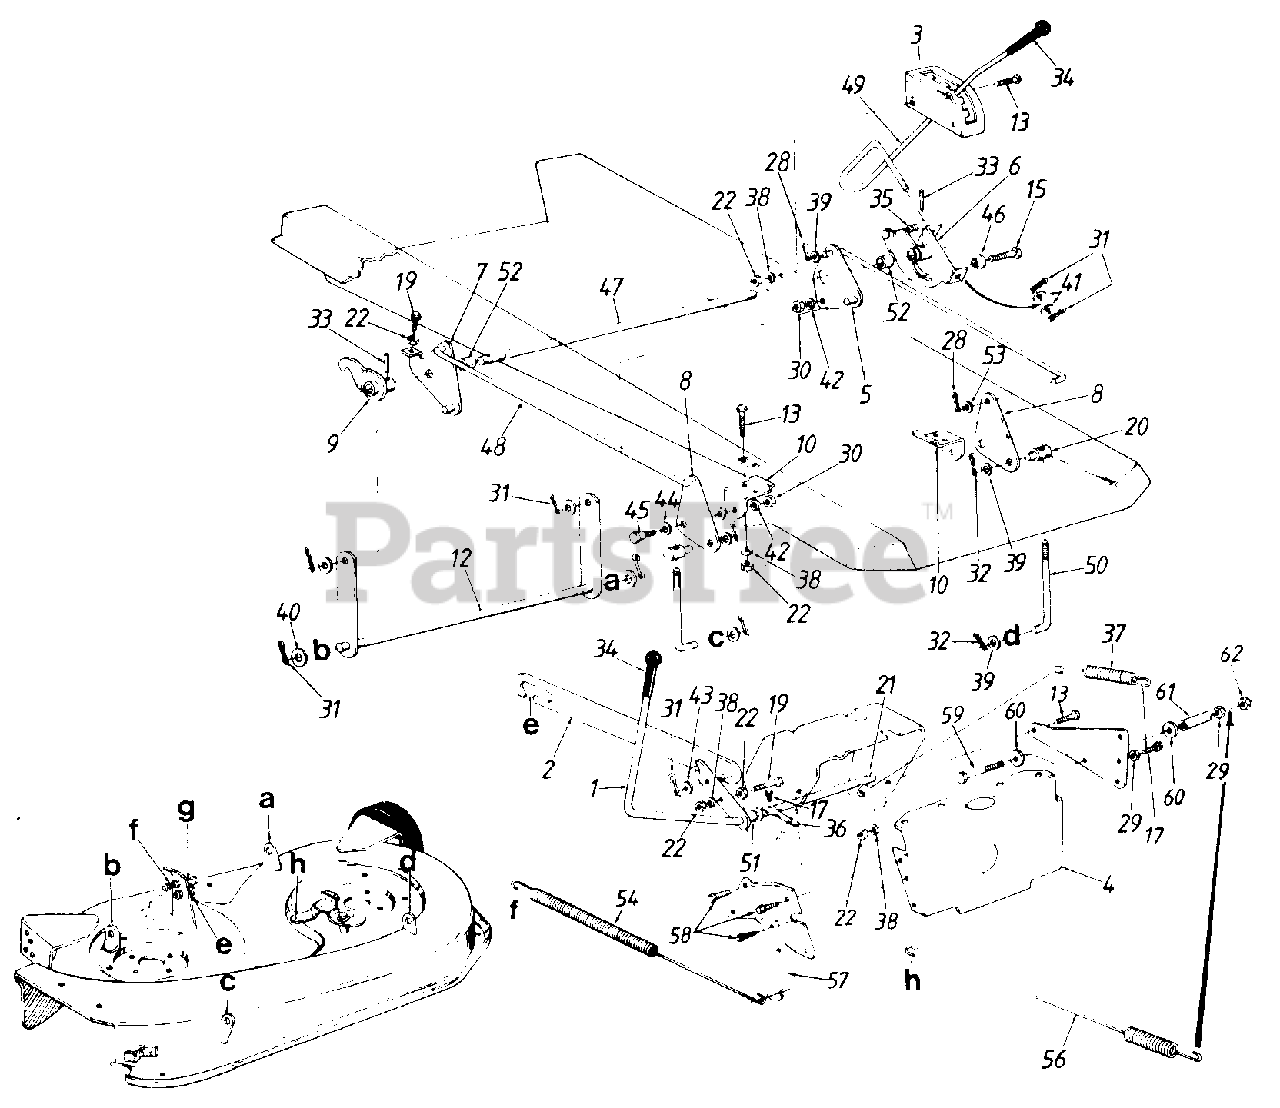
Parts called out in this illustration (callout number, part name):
1	Blade Engagement Lever Ass'y.
2	Deck Drive Control Brkt. Ass'y.
5	Deck Lift Brkt. Ass'y.
6	Deck Lift Handle Retainer Ass'y.
7	Deck Lift Brkt. Ass'y.
8	Deck Lift Bracket
9	Deck Lift Float Brkt Ass'y.
10	Deck Lift Pivot Brkt.
12	Stabilizer Shaft Ass'y.
13	Hex Bolt 5/16-18 x .75" Lg.
15	Hex Bolt 3/8-16 x 1" Lg.
17	Hex Wash. Hd. Scr. 1/4-20 x 1.5" Lg.
19	Hex Wash.-Tap Scr. 5/16-18 x 1.25" Lg.
20	Ferrule
21	Clevis Pin
22	Hex Nut 5/16-18 Thd.
28	Cotter Pin 3/32" Dia.
29	Hex Nut 1/4-20 Thd.
30	Hex Nut 3/8-16 Thd.
31	Cot-Pin 1/8" Dia. x 1" Lg.
32	Int. Cot. Pins 3/8" Dia.
33	Spring Pin Spir. 1/4" Dia.
35	Compression Spring 1.04"
36	Switch Actuator
37	Ext. Spring 5.86" Lg.
38	L-Wash 5/16" I.D.
39	Fl-Wash. .385 I.D. x .62
40	Fl-Wash. .635 I.D. x 1.12
41	Fl-Wash. .531 I.D. x .930
42	L-Wash. 3/8" I.D.
43	Fl-Wash. .385 I.D. x .87 O.D.
44	Spring Washer .530 I.D.
45	Shld. Bolt .500" Dia. x .215"
46	Shld. Spacer .625" I.D.
47	Rear Hot Adj. Shaft
50	J-Bolt 5.4" Lg.
51	Spacer.511 I.D.
52	Spacer .885 I.D.
53	Fl-Wash. 5/16" I.D.
54	Ext. Spring 22.05" Lg.
56	Ext. Spring 15.38" Lg.
57	Spring Anchor
58	Hex Wash. Hd. AB-Tap Scr. 1/4 x.62" Lg.
59	Hex Bolt 1/4-20 X 2.5" Lg.
60	Fl-Wash. .25" I.D. x .93"
61	Spacer .255" I.D.
62	1 Hex L-Nut 1/4-20 Thd.
